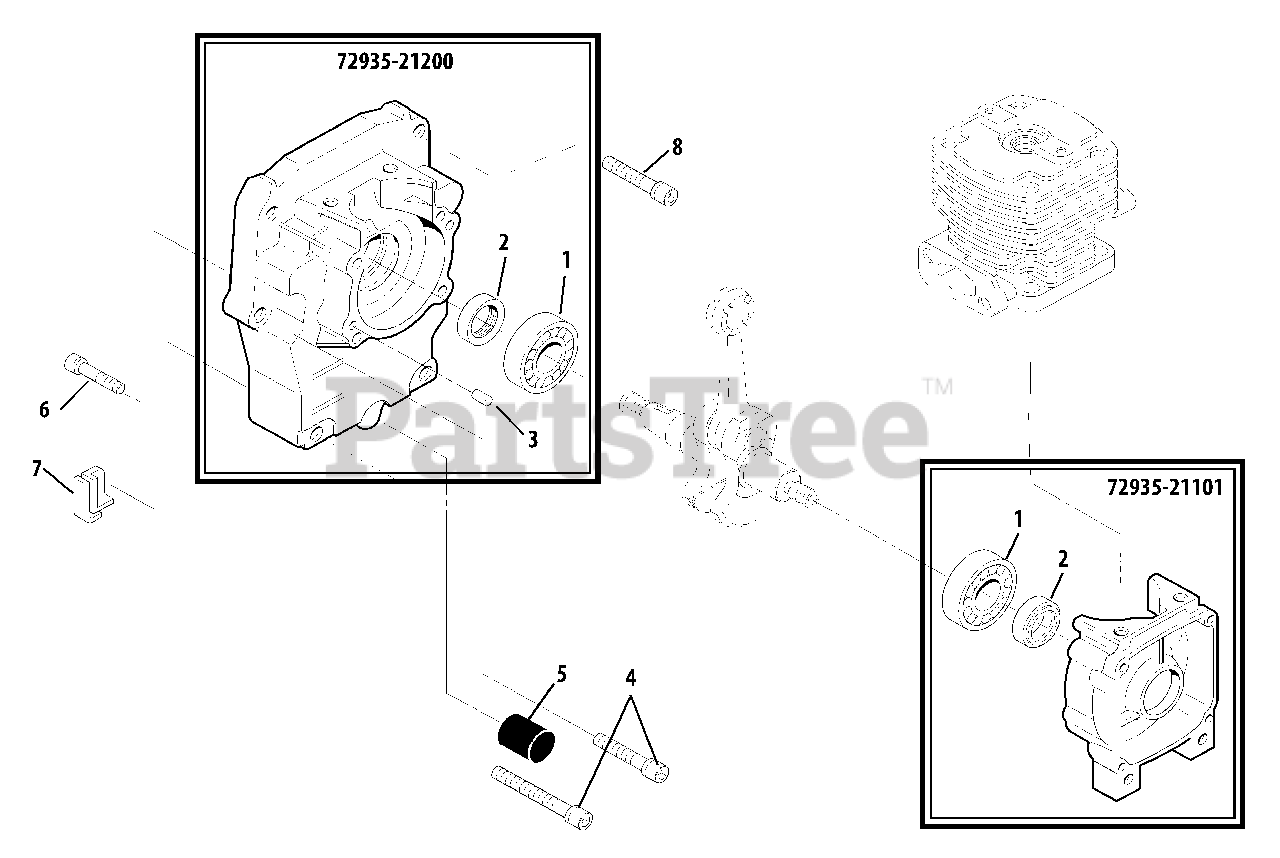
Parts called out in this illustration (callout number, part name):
1	BEARING, BALL - 6202
2	SEAL, OIL
3	PIN - LOCATING
4	SCREW - 6X45
5	CUSHION
6	SCREW - 5X30
7	SEAL
8	SCREW - 6X30
72935-21101	CRANKCASE ASSY - REAR
72935-21200	CRANKCASE ASSY - FRONT
